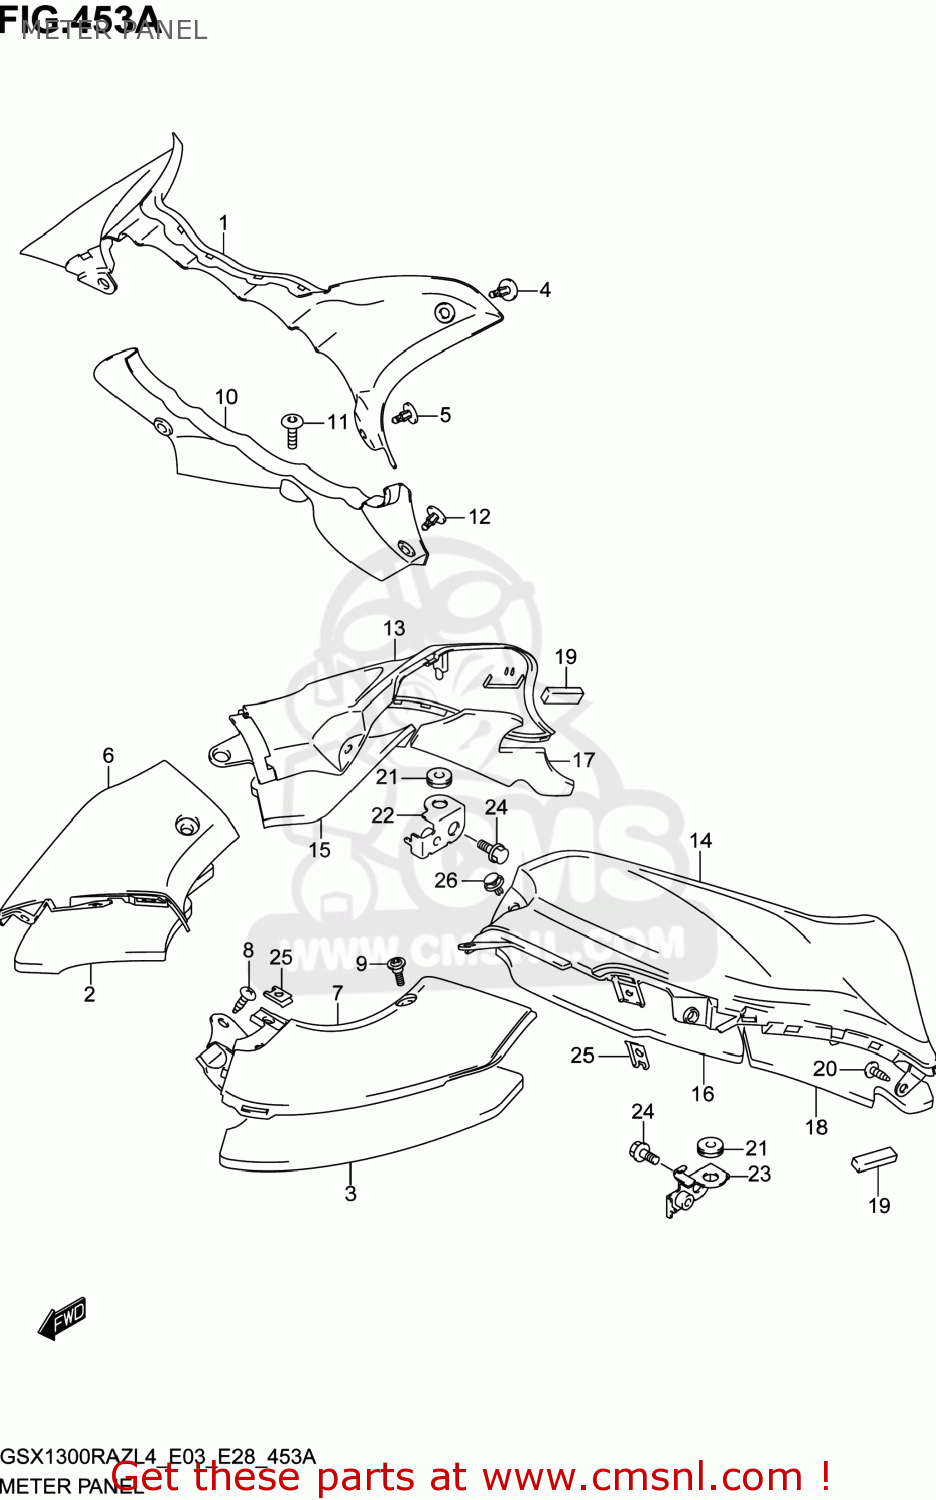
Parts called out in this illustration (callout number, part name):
1	PANEL,METER UPR
2	CUSHION,PANEL UPR,R
3	CUSHION,PANEL UPR,L
4	CLIP(BLACK)
5	CLIP
6	PANEL,UPR,R
7	PANEL,UPR,L
8	SCREW
9	SCREW(5X16)
10	PANEL,METER RR
11	SCREW(5X13)
12	CLIP
13	PANEL,SIDE,R
14	PANEL,SIDE,L
15	CUSHION,SIDE PANEL FR,R
16	CUSHION,SIDE PANEL FR,L
17	CUSHION,SIDE PANEL RR,R
18	CUSHION,SIDE PANEL RR,L
19	CUSHION
20	SCREW(5X16)
21	CUSHION,COVER SIDE FR,L
22	BRACKET,PANEL,R
23	BRACKET,PANEL,L
24	BOLT
25	NUT,COWL
26	CLIP
